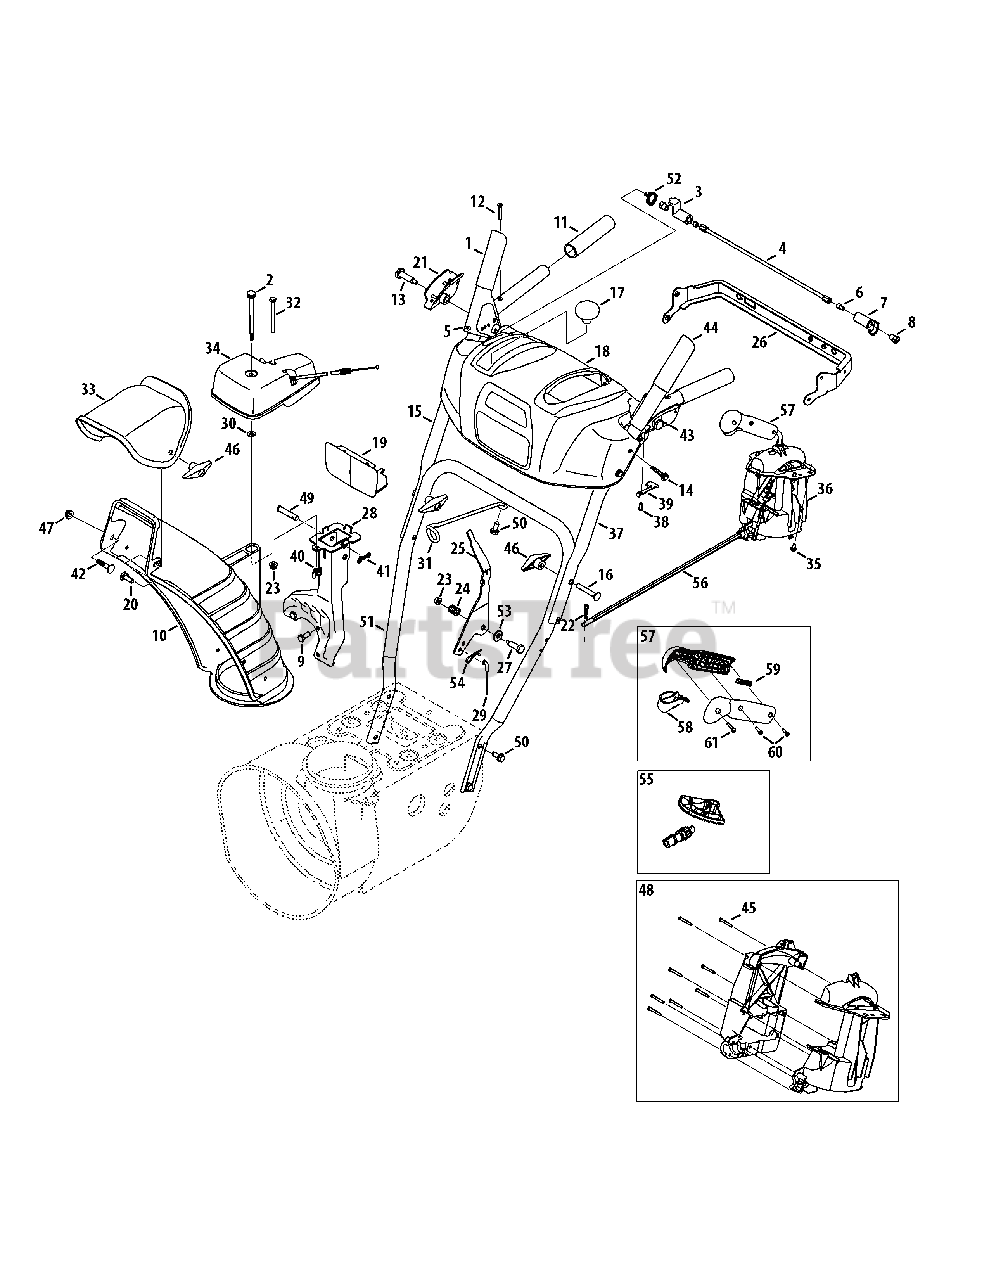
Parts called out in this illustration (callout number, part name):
1	Handle Engagement Ass’y RH
2	Flange Shoulder Screw
3	Lock Plate
4	Pivot Rod
5	Rubber Bumper
6	Screw, 1/4-20 x .500
7	Clutch Lock Cam
8	Shoulder Nut, 1/4-20
9	Hex Screw, 5/16-24 x .750
10	Lower Chute
11	Handle Grip
12	Screw, #10-24 x 0.375
13	Shoulder Screw, 1/4-20
14	Screw, 1/4-20 x 1.625
15	Upper Handle RH
16	Carriage Screw, 5/16-18 x 2.25
17	Shift Knob
18	Handle Panel
20	Carriage Bolt, 5/16-18 x 1.0
21	Handle Clutch Lock RH Assy
22	Cotter Pin
23	Flange Lock Nut, 1/4-20
24	Compression Spring
25	Shift Lever
26	Panel Bracket
27	Shoulder Screw
28	Chute Support Bracket
29	Speed Selector Cable
30	Flat Washer, .25 x .630 x .0515
31	Cable Guide
32	Hex Screw, 1/4-20 x 3.00
33	Upper Chute
34	Gearbox Assembly
35	Hi-Lo Screw, 1/4-15 x 0.5
36	2-Way Chute Control Assembly
37	Upper Handle LH
38	Screw, #8-16 x 0.50
39	Clutch Lock Spring
40	Wing Nut, 1/4-20
41	Bow Tie Cotter Pin
42	Carriage Bolt, 5/16-18 x .75
43	Handle Clutch Lock LH Assy
44	Handle Engagement Assembly LH
45	Screw, #8-18 x 1.250
46	Wing Knob
47	Flange Lock Nut, 5/16-18
48	Handle Housing Assembly
49	Clevis Pin
50	Screw, 5/16-18 x 0.75
51	Lower Handle
52	Torsion Spring
53	Flat Washer
54	Click Pin
55	Gear Set Assembly
56	Chute Rod
57	Handle Assembly
58	Handle Lever
59	Handle Plunger
60	Screw, Mach., #8-32 x .750
61	Screw, #8 x 1.00
